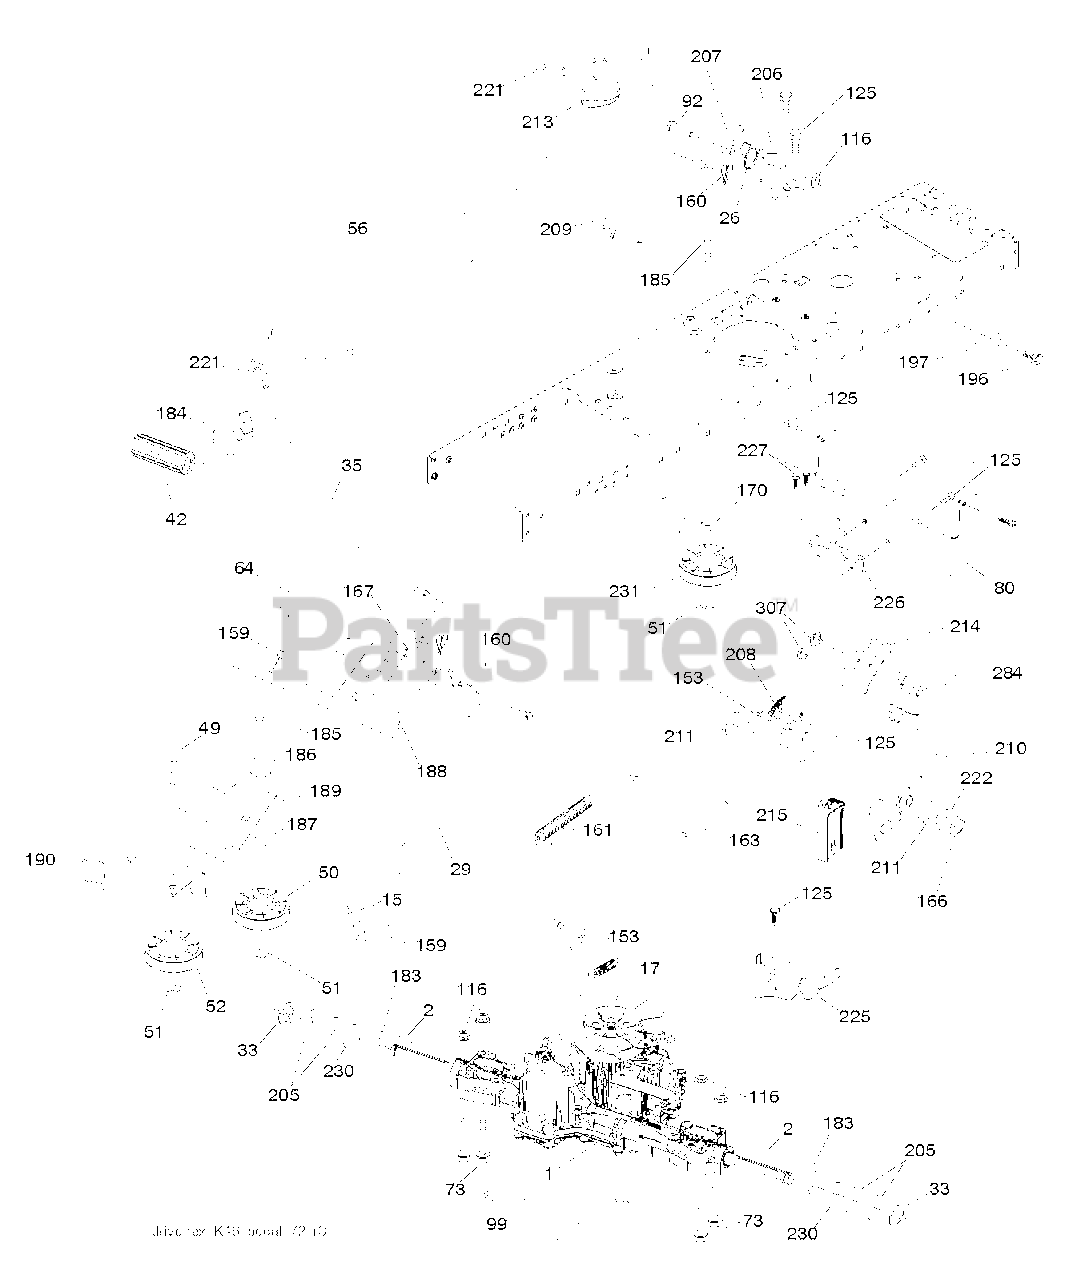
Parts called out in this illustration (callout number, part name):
2	SQUARE KEY
15	WASHER
17	SPRING.BRAKE.K46.GREEN
26	SPRING.RETURN.CRUISE
29	ROD.BRAKE.K46
35	ROD .BRAKE. PARKING. GT. HUSQ.
42	PEDAL COVER T
50	IDLER.FLAT.910.OFFSET
51	NUT LOCK FLG 3/8-16 UNC
52	IDLER.V-GROOVE.910.OFFSET
56	V-BELT.MOWER.92.40.42/K46
64	SHAFT.ASM.PEDAL.BRK.CNTR
80	STRAP.TORQUE.K46.K57R.TT
92	BOLT
99	ROD.SPRING.BYPASS.K46.LT.Z
116	NUT LOCK HEX FLANGE 5/16-18
125	SCREW
153	RETAINER M
159	COTTER PIN
160	RETAINER CLIP
161	SPRING, RETURN LT
163	ROD.CONTROL.K57R.K46
166	NUT.PUSH.625
167	LATCH.BRAKE.SPRING
170	KEEPER.CENTER SPAN.1.688
183	SPACER AXLE
184	RB HANDLE.PARKG.BRK.HUS/PRED
186	SPACER.RETAINER
187	WASHER 12/32X2X10GA
188	RP LINK.CLUTCH.GROUND.DRIVE
189	BELLCRANK.GROUND.DRIVE.TEX.
190	KEEPER.BELLCRANK.DRIVE
196	SCREW 3/8-16X1
197	LINK.CLUTCH.ANIT-ROTAT
206	BRACKET.MOUNT.CRUISE.LATCH
207	LATCH.CONTROL.CRUISE
208	GEAR.SECTOR.CONTROL.CR
209	ROD.CONTROL.CRUISE.GT.
210	ROCKER.ASM.PEDAL.CONTR
211	BEARING.NYLON
213	KNOB.CONTROL.CRUSIE.HU
214	PEDAL.FORWARD.HUSQVARNA.DEALER
215	PEDAL.REVERSE.TEX.GT.4
221	RETAINER.SPRING.CLIP.H
222	WASHER 21/32 X 1-1/4 X 10 GA.
225	KEEPER.BELT.TRANSAXLE.K46
226	BRACKET.MOUNT.TORQUE.K46.TLT
227	SCREW
230	WASHER.HARDENED
231	IDLER.V-GROOVE.1.688.OFFSET
284	NUT.U-CHNL.1/4-20.550DP.350PNL
307	SCREW.MACHINE.CR.1/4-20
